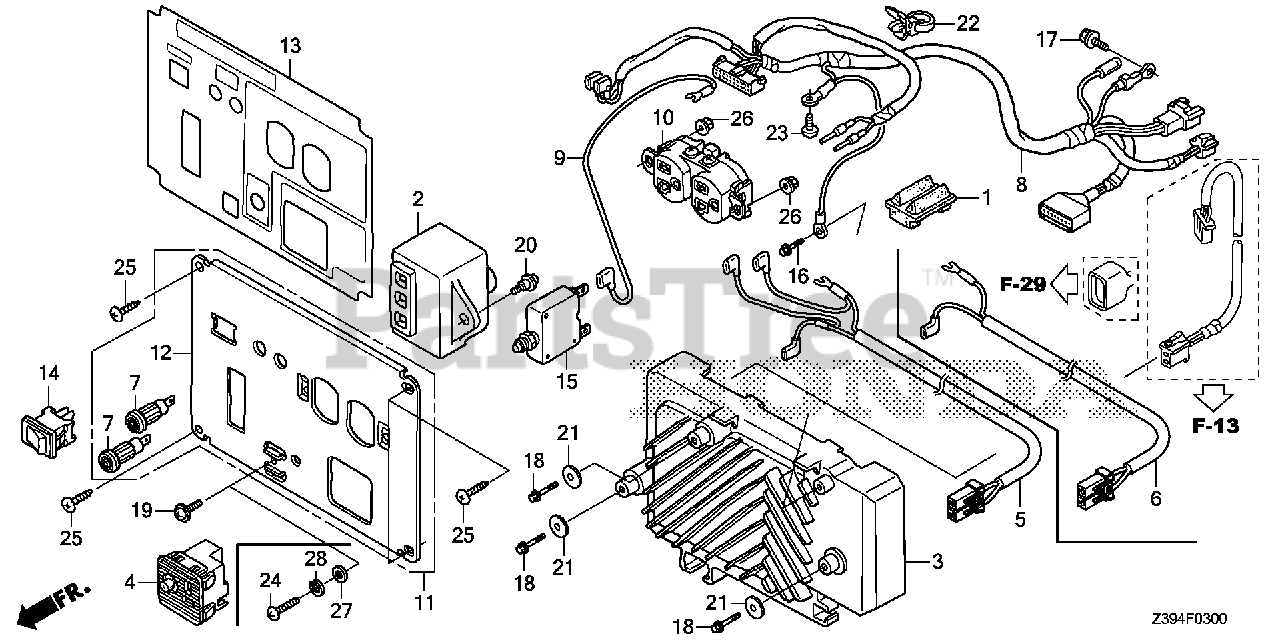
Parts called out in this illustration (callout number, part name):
1	RUBBER B, TANK MOUNTING
2	SPARK UNIT
3	INVERTER UNIT
4	RECEPTACLE, D.C.
5	SUB-WIRE HARNESS ASSY.
7	SOCKET, COMPOSITE
8	WIRE HARNESS ASSY., CONTROL
9	WIRE, TERMINAL
10	RECEPTACLE ASSY. (20A/125V) (MATSUSHITA)
11	PANEL, CONTROL
12	PANEL, CONTROL
13	MARK, CONTROL PANEL
14	SWITCH, AUTO-THROTTLE
15	PROTECTOR, CIRCUIT (20A) (WHITE)(TYCO)
15	PROTECTOR, CIRCUIT (20A) (BLACK)(JOEMEX)
16	BOLT, FLANGE (5X10)
17	BOLT, FLANGE (5X10) (CT200)
18	BOLT, FLANGE (5X12)
19	SCREW, PAN (5X12)
20	SCREW, PAN (5X13)
21	WASHER, PLAIN (20MM)
22	BAND (100MM) (BLACK)
23	SCREW, PAN (5X8)
25	SCREW, TAPPING (5X16) (PO)
26	NUT, FLANGE (4MM)
